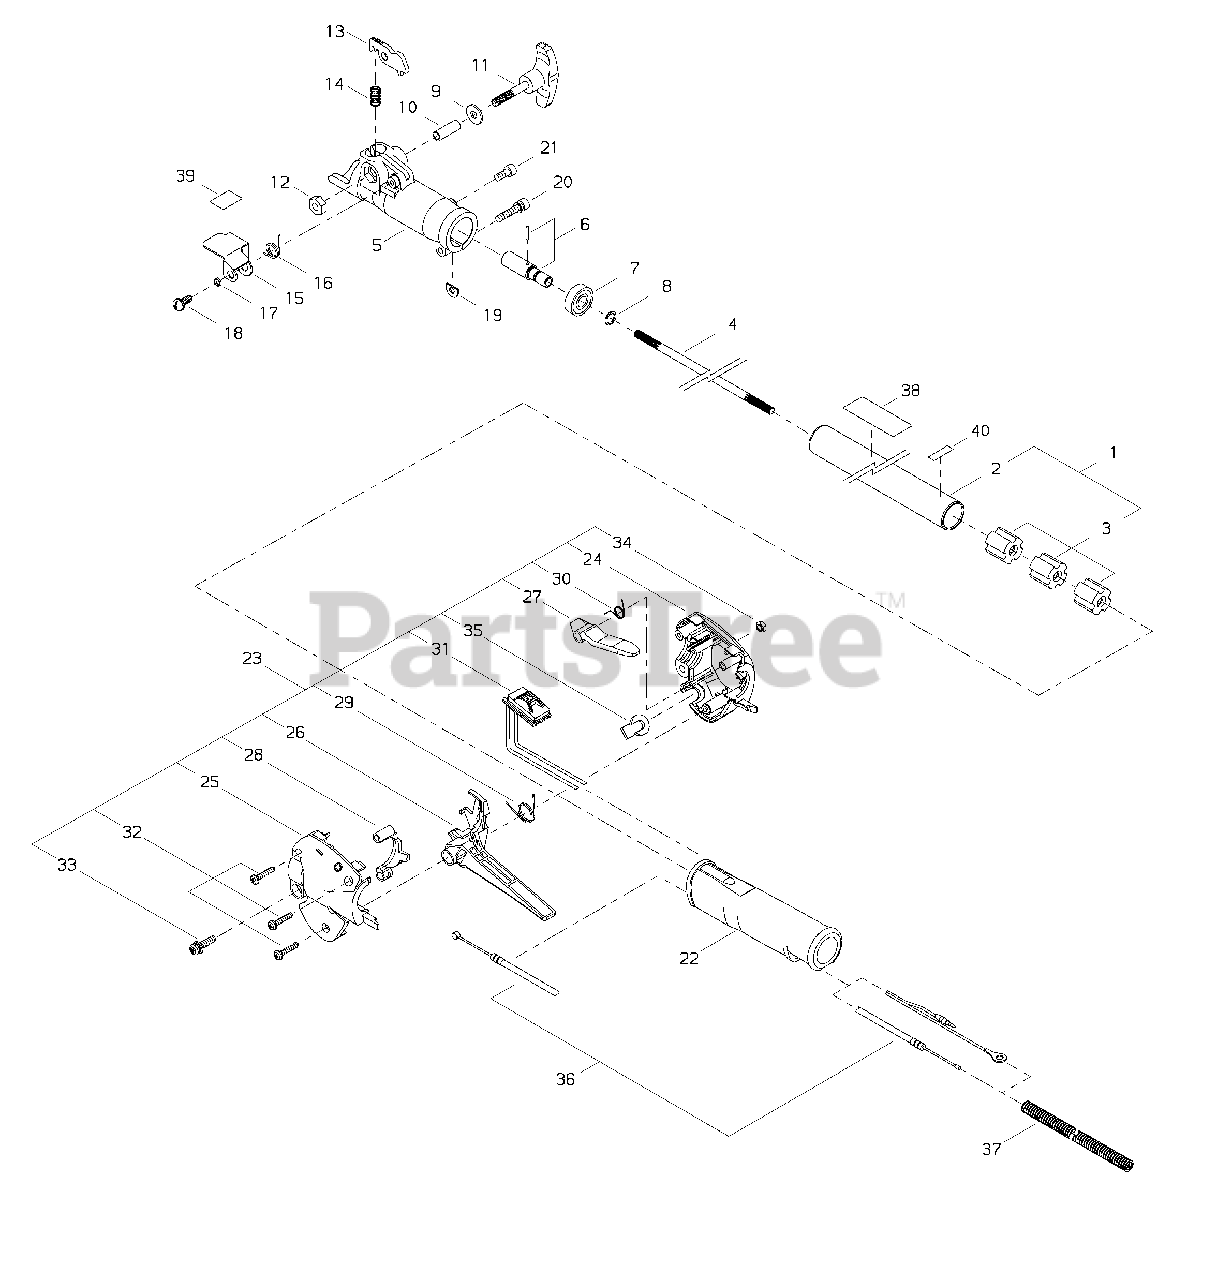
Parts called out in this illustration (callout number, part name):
1	MAIN PIPE ASSY
2	PIPE, MAIN
3	BUSHING
4	MAINSHAFT
5	HOUSING, COUPLER
6	SHAFT, COUPLER
7	BEARING, BALL 609ZZ
8	RING, SNAP
9	WASHER 6
10	COLLAR
11	KNOB, COUPLER SCREW
12	NUT 6
13	LATCH
14	SPRING
15	PROTECTOR, LATCH
16	SPRING, TORSION
17	WASHER 5
18	SCREW M5×12
19	D-WASHER
20	BOLT M5×25
21	BOLT 5×12
22	GRIP, REAR
23	THROTTLE CONTROL ASSY
24	CONTROL HANDLE - RIGHT
25	CONTROL HANDLE - LEFT
26	TRIGGER, THROTTLE
27	LEVER, THROTTLE LOCKOUT
28	LOCKOUT, THROTTLE
29	SPRING, THROTTLE RETURN
30	SPRING, THROTTLE LOCKOUT
31	SWITCH, ON-OFF
32	SCREW, TAPPING M4×20
33	SCREW M5×20
34	NUT M5
35	PLUG
36	CABLE, THROTTLE
37	TUBE, PLASTIC PROTECTIVE
38	LABEL, CAUTION
39	LABEL, LATCH INSTRUCTION
40	LABEL, HANDLE
